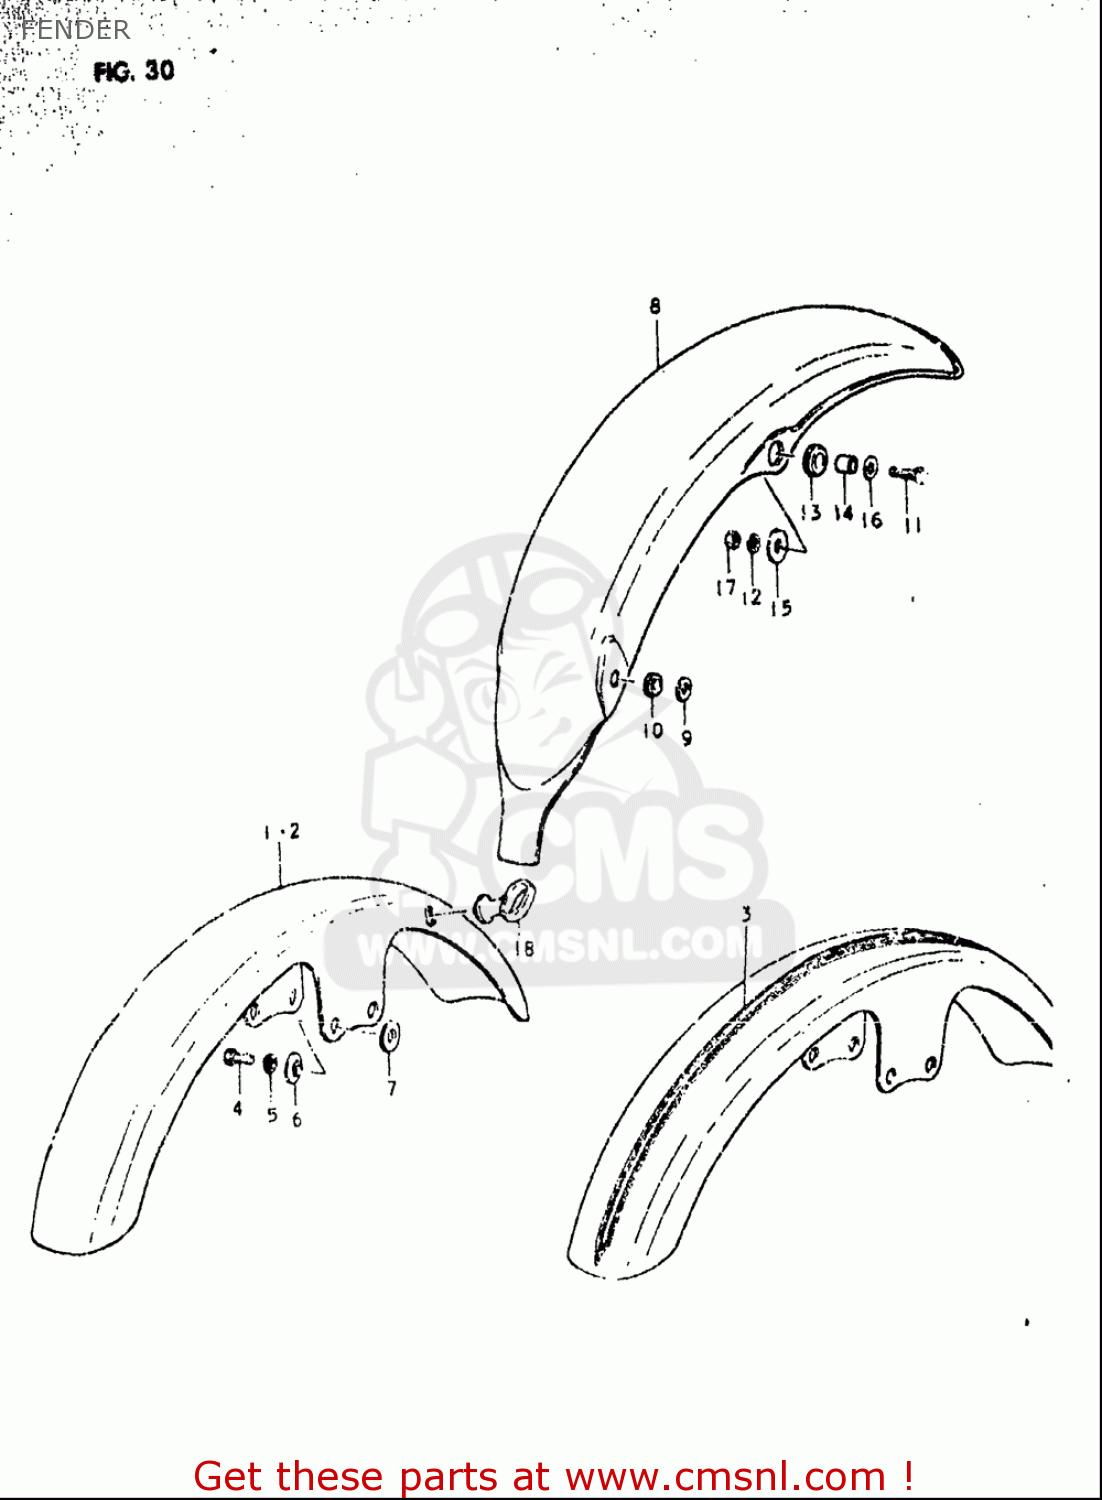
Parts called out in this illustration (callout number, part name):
4	BOLT
5	WASHER,LOCK
6	WASHER(6.5X24X1.2)
7	WASHER
8	FENDER,REAR
9	WASHER(6.5X18X1.6)
10	CUSHION
11	BOLT
12	WASHER,LOCK
13	CUSHION
14	SPACER(8.5X12X7.5)
15	WASHER(8.5X26X1.2)
16	WASHER
17	NUT
18	GUIDE,CABLE
